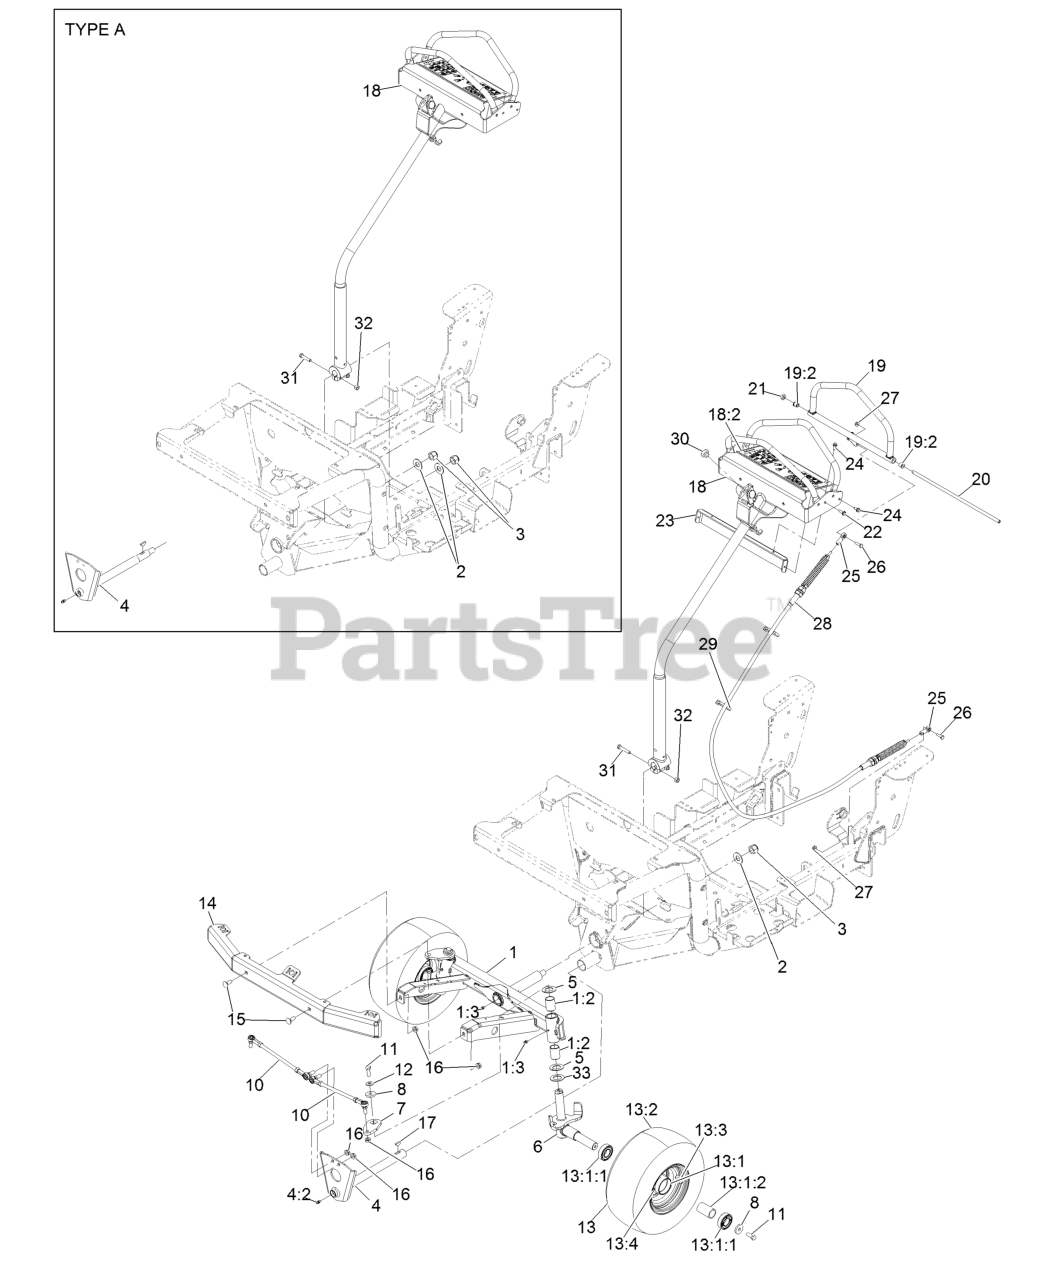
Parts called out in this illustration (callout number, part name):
1	Front Axle ASM
1:2	Bearing-Sleeve
1:3	Zerk-Grease
2	Washer-Flat
2	Washer-Flat (Type A)
3	Nut-Hex Nyloc 5/8-11 SS
3	Nut-Hex Nyloc 5/8-11 SS (Type A)
4	Steering Shaft ASM
4	Steering Shaft ASM (Type A)
4:2	Zerk-Grease
5	Washer-Thrust
6	Front Axle ASM
7	Arm-Steering
10	Steering Linkage ASM
11	Screw-HH
12	Washer-Spring Disc 3/8
13	Wheel And Tire ASM
13:1	Wheel ASM
13:1:1	Bearing-Ball
13:3	Stem-Valve
13:4	Fitting-Grease
14	Bumper-Front
15	Screw-Carriage 3/8-16 X 1 SS
16	Nut-Hex Flg
17	Key-Woodruff
18	Motion Handle ASM
18	Motion Handle ASM (Type A)
18:2	Decal-Warning
19	Motion Handle ASM
19:2	Bearing
20	Shaft-Pivot, Speed Control
21	Spacer-Shaft, Drive Lever
22	Screw-Hex Flange 1/4-20 X 3/4
23	Panel-Rear, Steering
24	Screw-HWH 1/4-20 X .62
25	Rod End-Ball Joint
26	Screw-HH 1/4-20 X 7/8 SS
27	Nut-Hex Flg
28	Cable-Motion
29	Tie-Cable 7 15/16 (Large)
30	Bumper-Rubber
31	Screw-HH
32	Nut-Hex 5/16-24
33	Spacer-Relief
